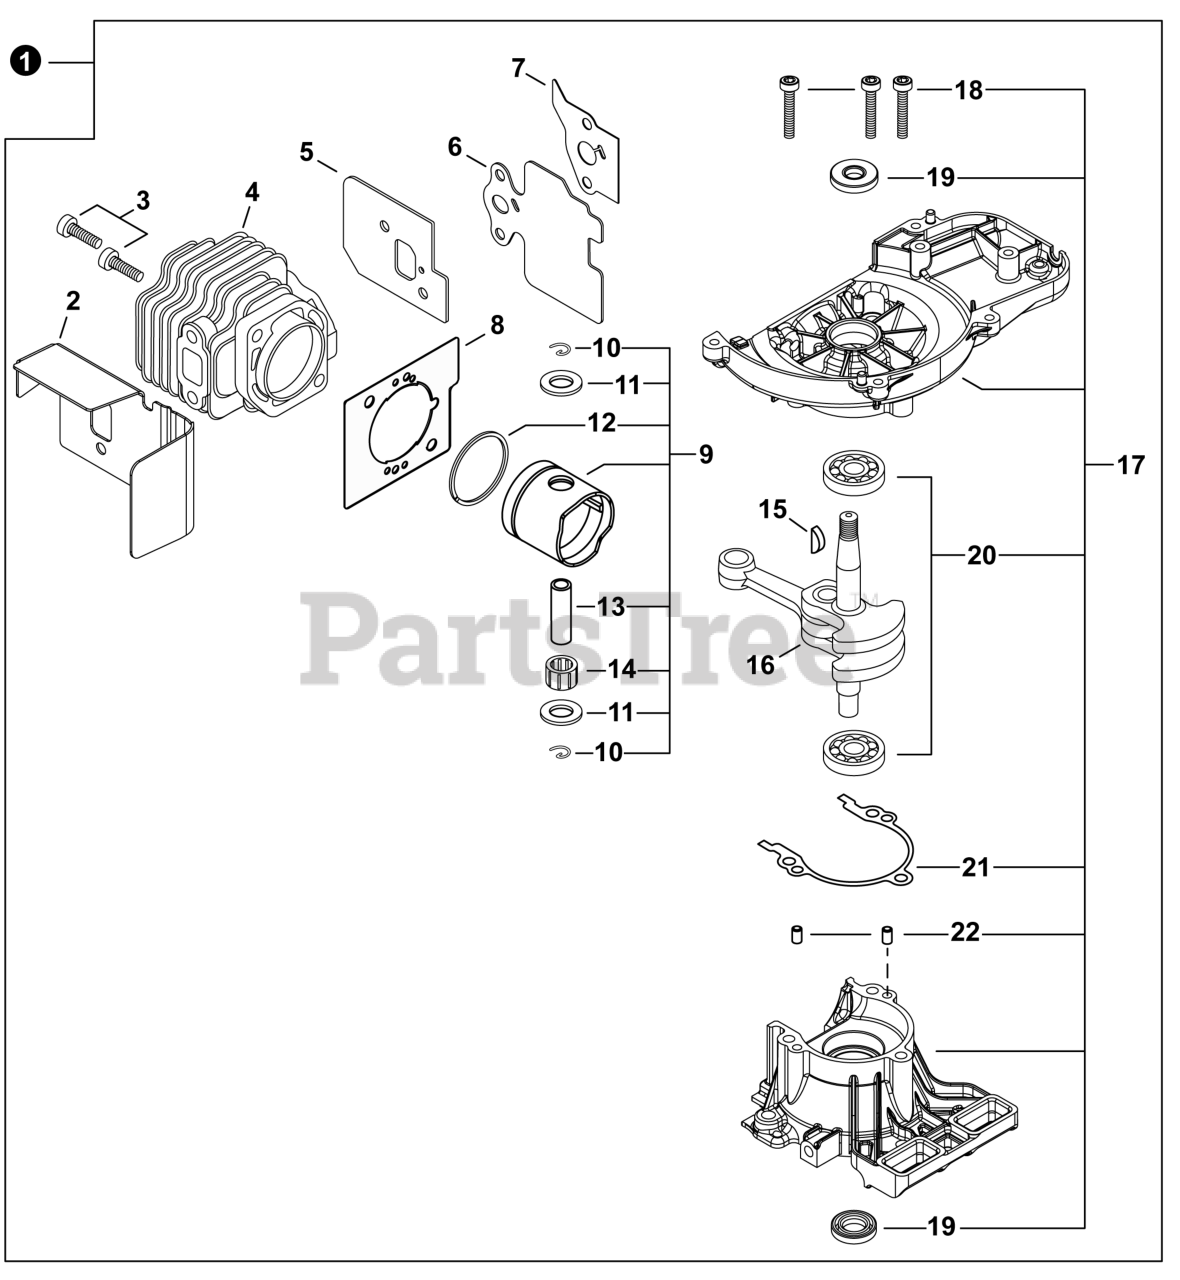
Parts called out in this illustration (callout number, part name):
1	SHORT BLOCK
2	HEAT SHIELD, EXHAUST
4	CYLINDER
5	GASKET, INTAKE
6	HEAT SHIELD, INTAKE
7	GASKET, INTAKE
8	GASKET, CYLINDER
9	PISTON KIT
10	RING, SNAP
11	WASHER, THRUST
12	RING, PISTON
13	PIN, PISTON 8
14	BEARING, NEEDLE
15	KEY, WOODRUFF
16	CRANKSHAFT ASSY
17	CRANKCASE KIT
18	BOLT 5x28
19	SEAL, OIL
20	BEARING, BALL
21	GASKET, CRANKCASE
22	PIN, LOCATING 4x8
